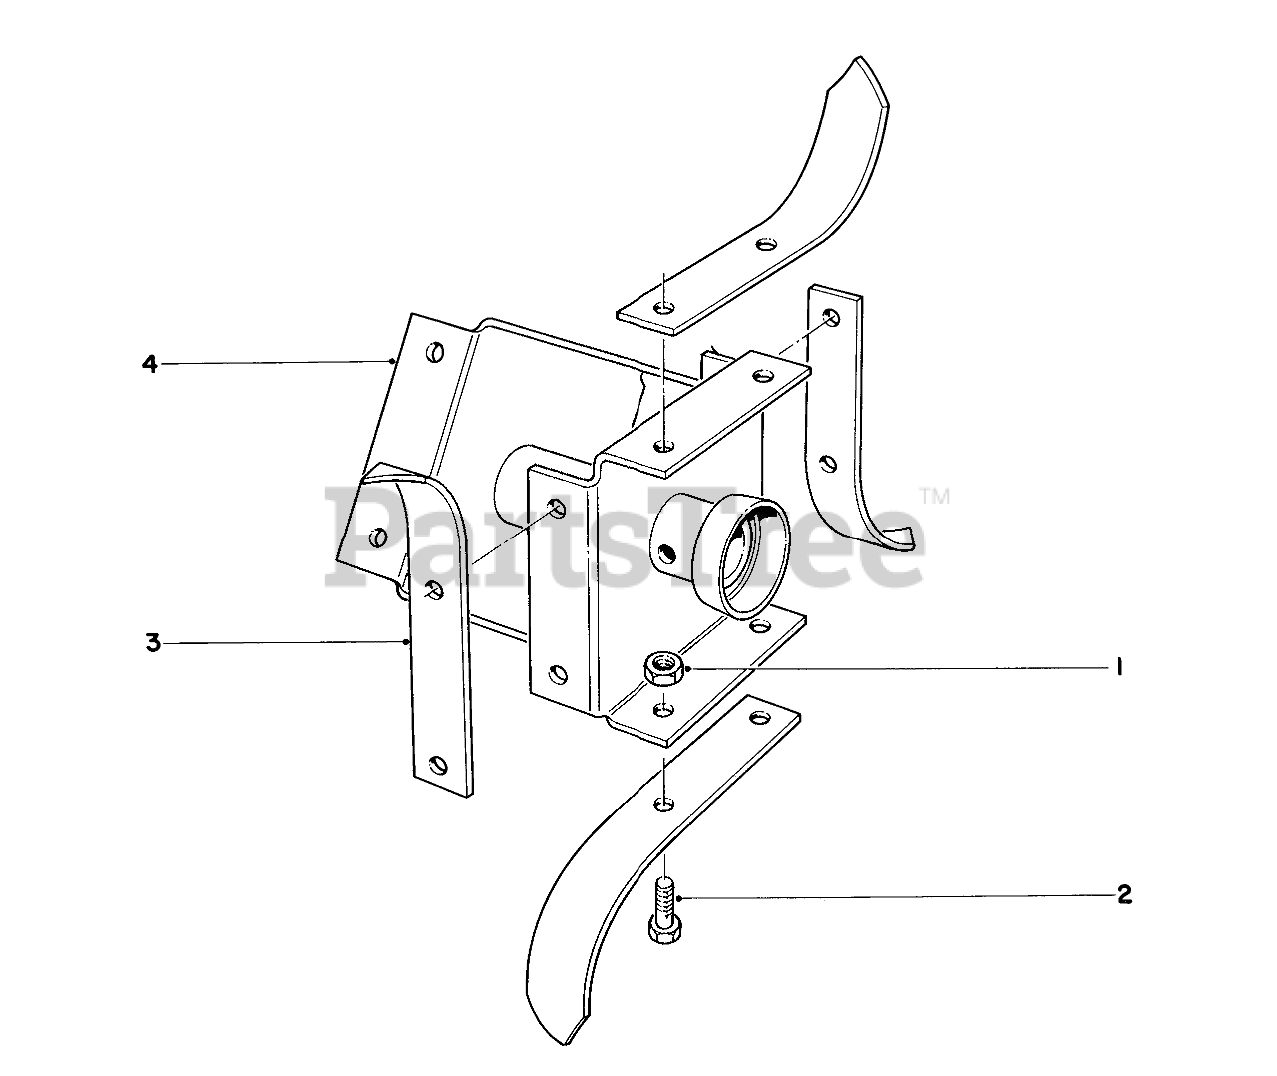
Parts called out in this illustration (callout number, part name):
1	NUT-LOCK, CONE
2	SCREW-HH
3	Pick Tine
4	Axle Welded R.H.
